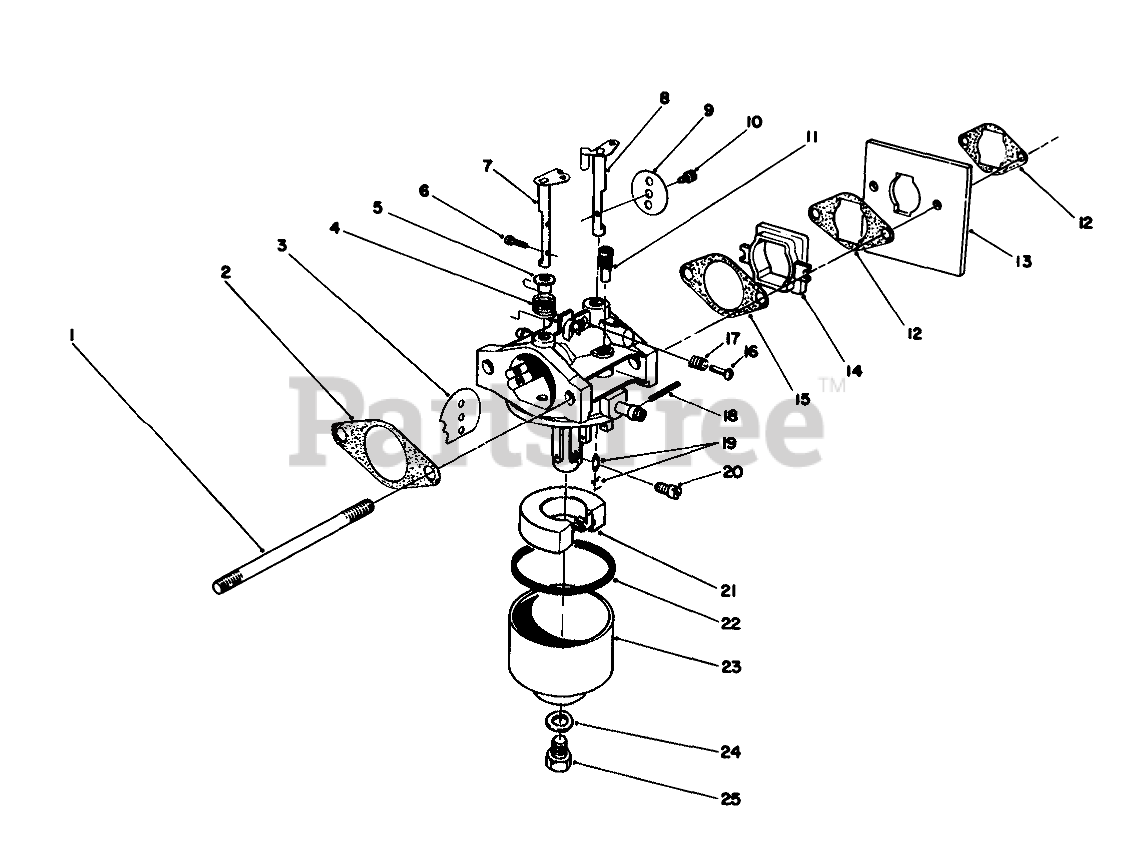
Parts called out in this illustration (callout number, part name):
1	CARB STUD BOLT
2	GASKET-AIR CLEANER
3	CHOKE VALVE
4	Spring-Choke
5	BUSHING
6	SCREW
7	SHAFT-CHOKE
8	SHAFT
9	PLATE
10	Screw-Throttle
11	PILOT JET
12	GASKET
13	SHIELD
14	INSULATOR
15	GASKET-CARB
16	SCREW
17	SPRING-PILOT SCREW
18	Pin
19	NEEDLE
20	MAIN JET (76.3)
21	FLOAT
22	GASKET
23	BOWL - FLOAT
24	Gasket-Bowl Screw
25	SCREW
